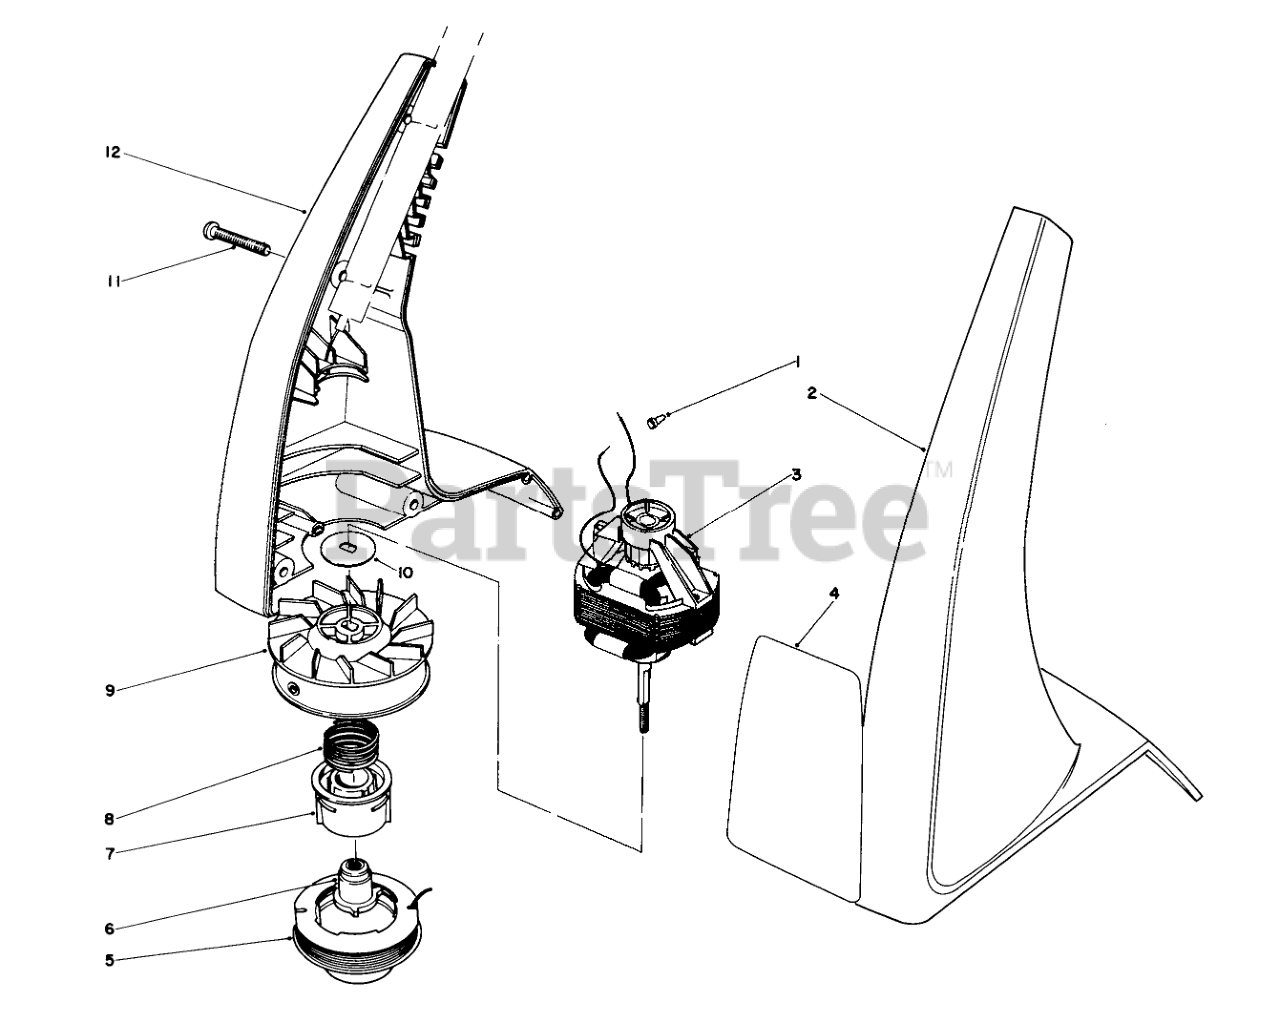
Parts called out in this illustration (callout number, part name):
5	Prewound Spool
6	DRIVER
7	CORE - SPOOL
8	SPRING-COMPRESSION
